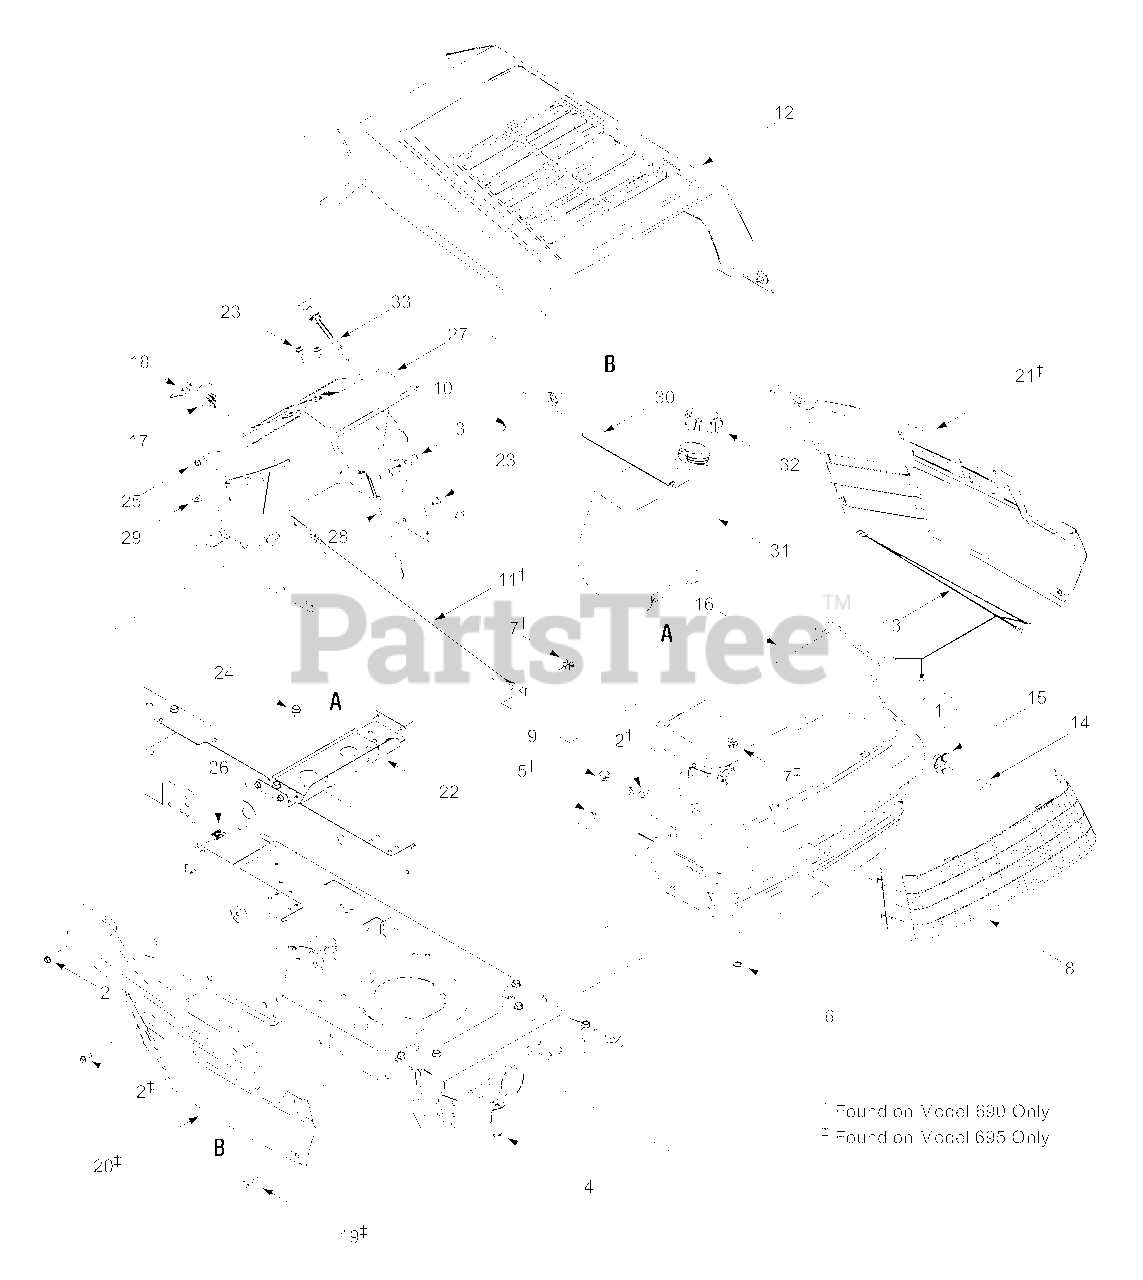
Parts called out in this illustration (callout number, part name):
1	Grille Assembly
2	Self-tapping Screw, 1/4-20 x .75
3	U-type Speed Nut, 1/4-20
4	Flange Lock Nut, 5/16-18
5	Flange Lock Nut, 1/4-20
6	Speed Nut, .3125
7	Push-on Nut, .25
8	Lens
9	Shoulder Screw, 5/16-18 x .625
10	Shoulder Screw, 1/4-20 x .375 /.125
14	Headlamp, 12V
15	Headlamp Socket
16	Grille
17	Ignition Switch, 6-pin
18	Keys (pair)
19	Hex Screw, 1/4-20 x .620
23	Self-tapping Screw, 1/4-20 x .5
24	Self-tapping Screw, 5/16-18 x .5
25	Self-tapping Screw, 1/4-20 x 1.0
26	U-type Speed Nut, 1/4-20
27	Dash Panel (models w/o choke knob)
28	Throttle / Choke Control, 18.5"
29	Flat Washer, .260 x .720 x .060
30	Cable Tie, 30.66
31	Fuel Tank, 1.5 gal.
32	Fuel Tank Cap
33	Choke Control, 38"
